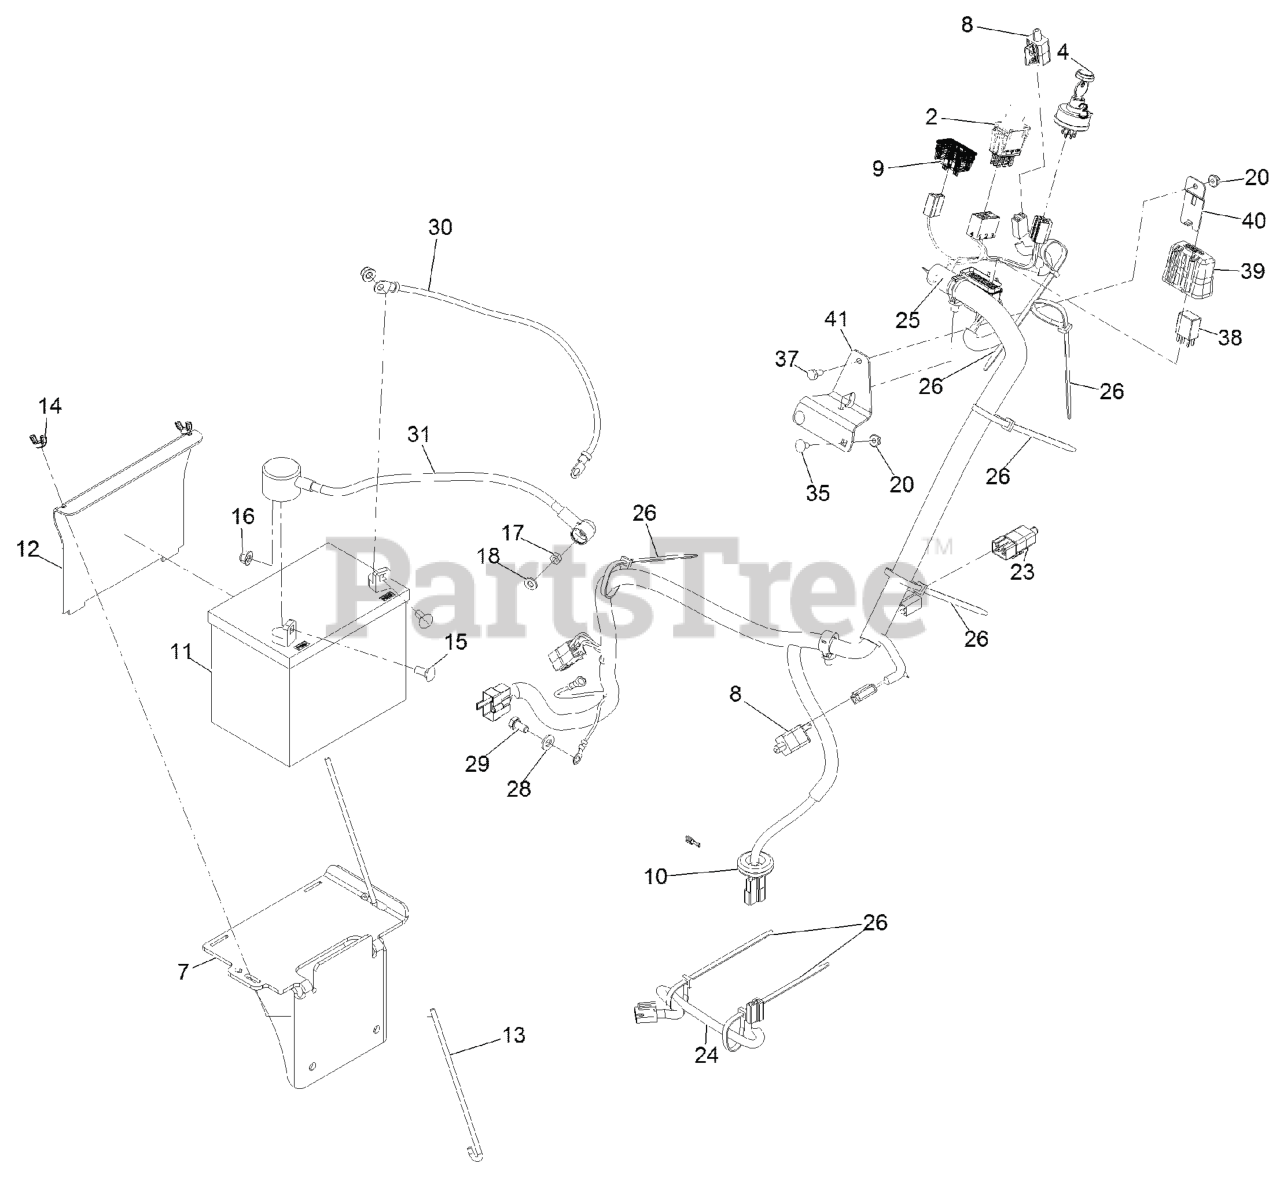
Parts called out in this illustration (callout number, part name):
2	SWITCH-PTO
3	SWITCH, KEY START
4	NUT-SWITCH, IGNITION
7	WELD, BATTERY MOUNT
9	METER-HOUR
10	GROMMET
11	Battery
12	BRACKET, BATTERY HOLD DOW
13	BOLT-HOLDDOWN
14	WINGNUT
15	BOLT-CARR
16	NUT-HF, NI
17	NUT-HEX
18	WASHER-FLAT
23	SWITCH, 2 POLE
24	HARNESS-CLUTCH PIGTAIL
25	HARNESS-WIRING
26	TIE-PLASTIC
28	WASHER-PLAIN
29	SCREW-HH
31	ASM,POSITIVE BATTERY CABL
35	SCREW-CARR
37	SCREW-HH
38	RELAY-MICRO 280, SPDT
39	COVER-BLOCK, FUSE
40	CLIP-MOUNTING
41	BRACKET-MOUNTING, FUSEBLO
